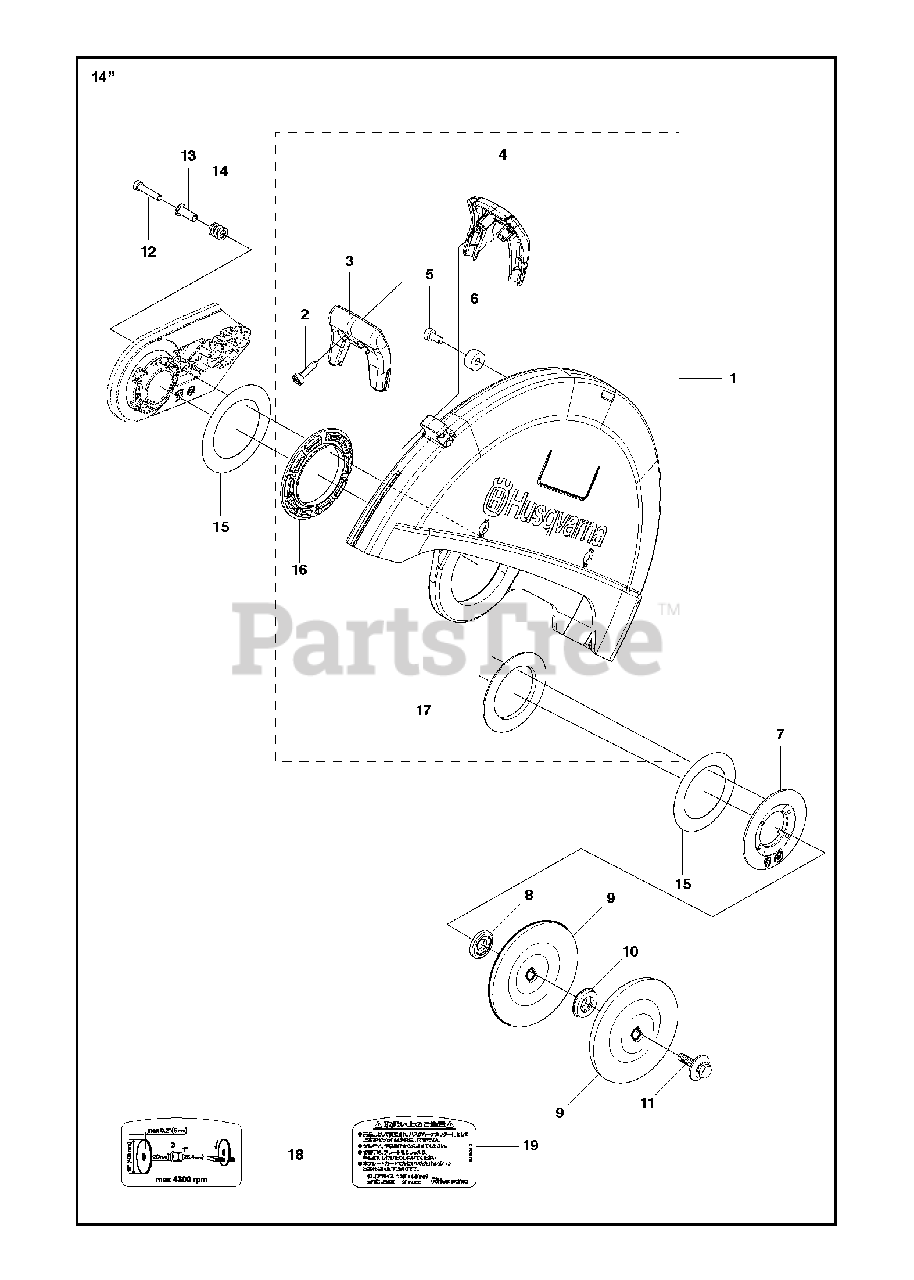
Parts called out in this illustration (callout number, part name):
1	WHEEL GUARD"14"""
2	SCREW ITXSCT
5	SCREW ITXSCT
8	SUPPORT FLANGE
9	FLANGEDiam 105mm
9	FLANGE WASHER"Diam 119mm, Japan 14""/16"""
10	BUSHINGDiam 20/25,4mm
10	BUSHINGDiam 30,5mm
10	KITDiam 22,2mm
12	SCREW ITXSCM
13	SLEEVE"14"""
18	DECAL"14"""
